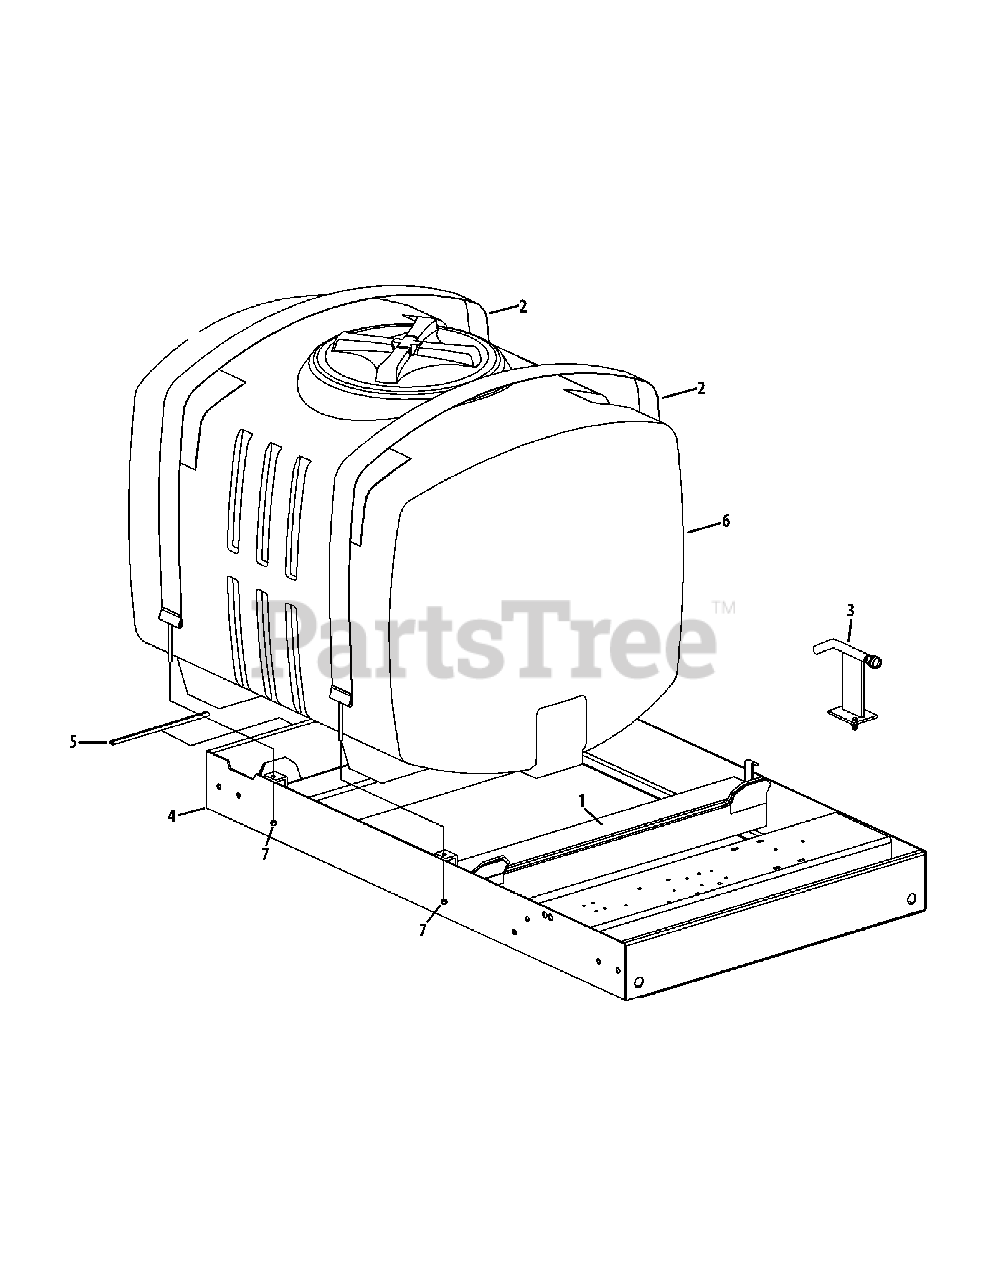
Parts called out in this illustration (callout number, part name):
1	Adhesive Backed Foam
2	Tank Strap
3	Air Gap Filler
6	Tank Assembly
7	Hex Lock Nut, 5/16-18
